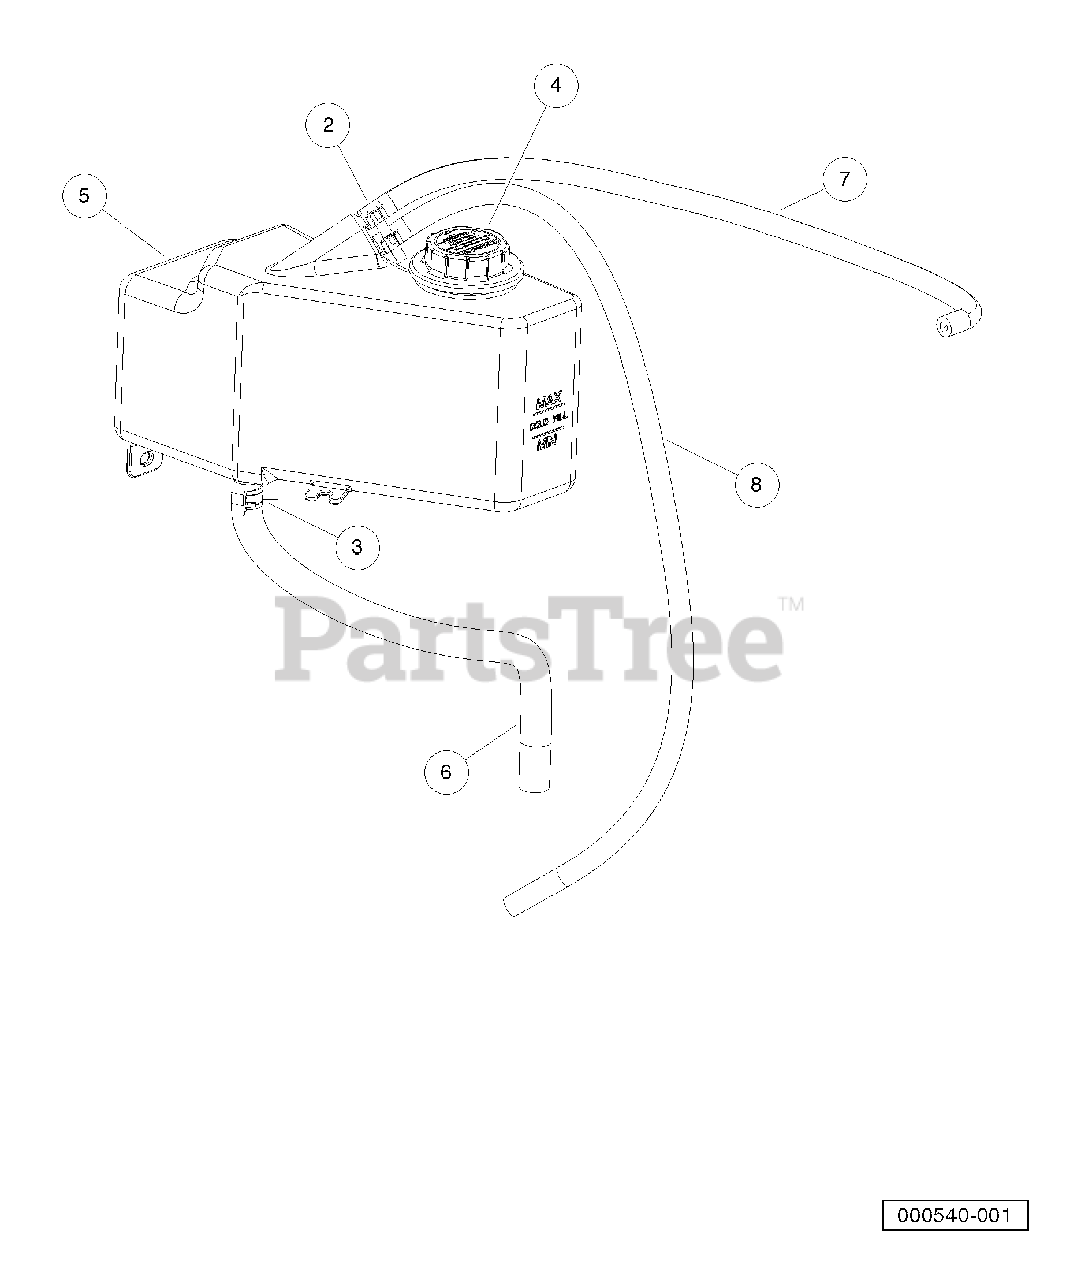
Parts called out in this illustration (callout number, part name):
1	Asm, Coolant Bottle
2	Clamp, Hose, CTB 15mm
3	Clamp, Hose, CTB 22mm
4	Cap, Radiator
5	Bottle, Coolant
6	Hose, Cut, 5/8, 445
7	Hose, Cut, Coolant, 700
8	Hose, Cut, Coolant, 1100
